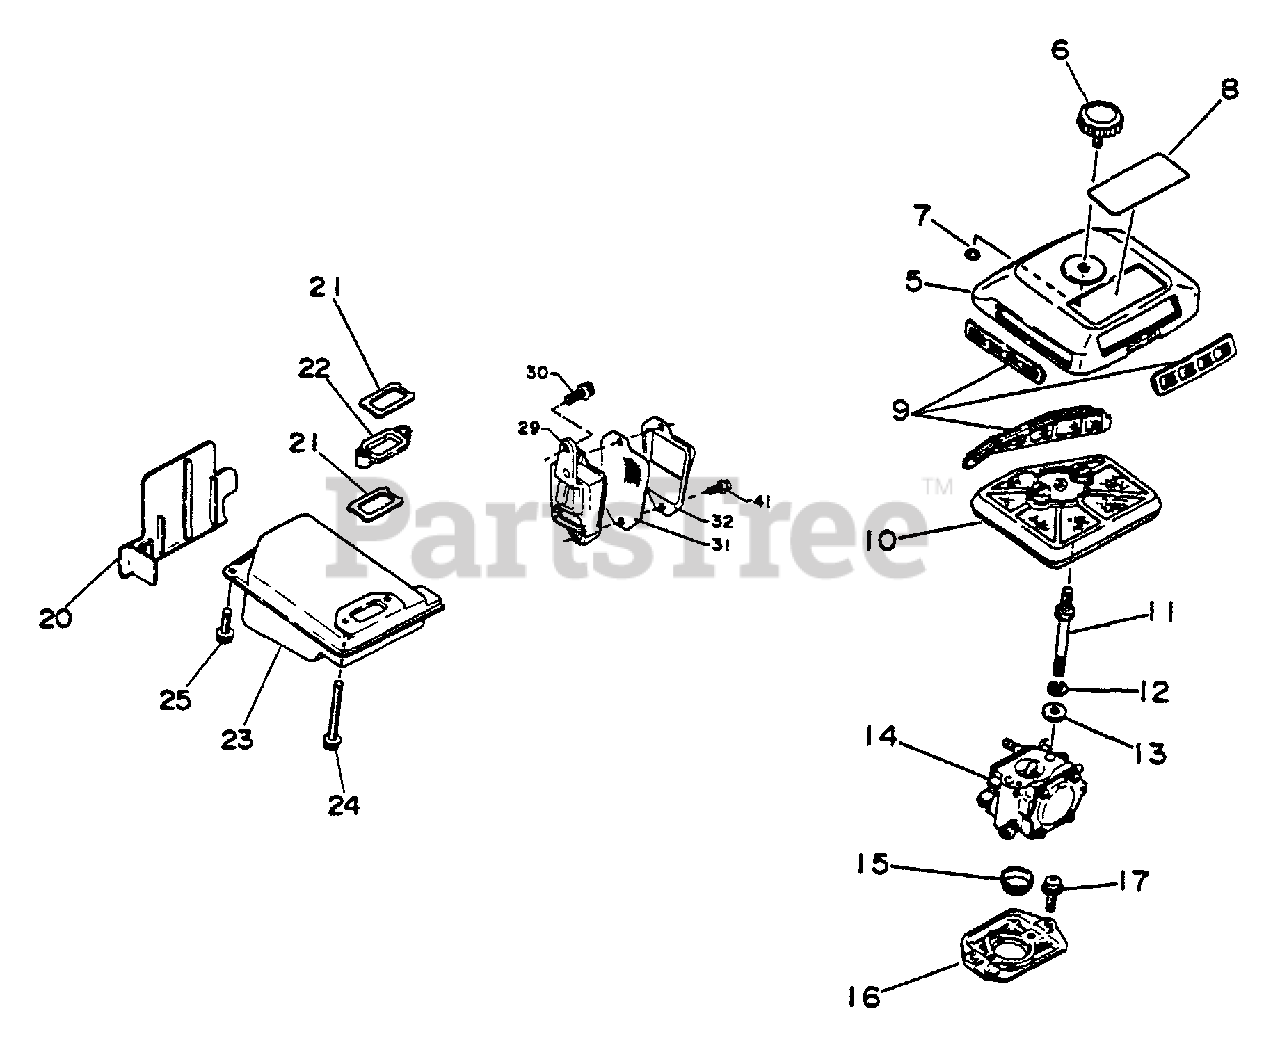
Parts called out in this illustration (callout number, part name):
5	COVER, AIR FILTER
6	THUMBSCREW
7	O-RING 3
8	LABEL
9	DEBRIS FILTER KIT
10	FILTER, AIR
11	SCREW
12	WASHER, SPRING 5
13	WASHER
14	CARBURETOR - HAD-20B
15	HOLDER
16	ADAPTER
17	SCREW 4×12
20	INSULATOR
21	GASKET, EXHAUST
22	BAFFLE, MUFFLER
23	MUFFLER
24	BOLT 5×45
25	BOLT 5×20
30	BOLT 5×14
31	SCREEN, SPARK ARRESTER
32	GUIDE, EXHAUST
41	SCREW 4×10
